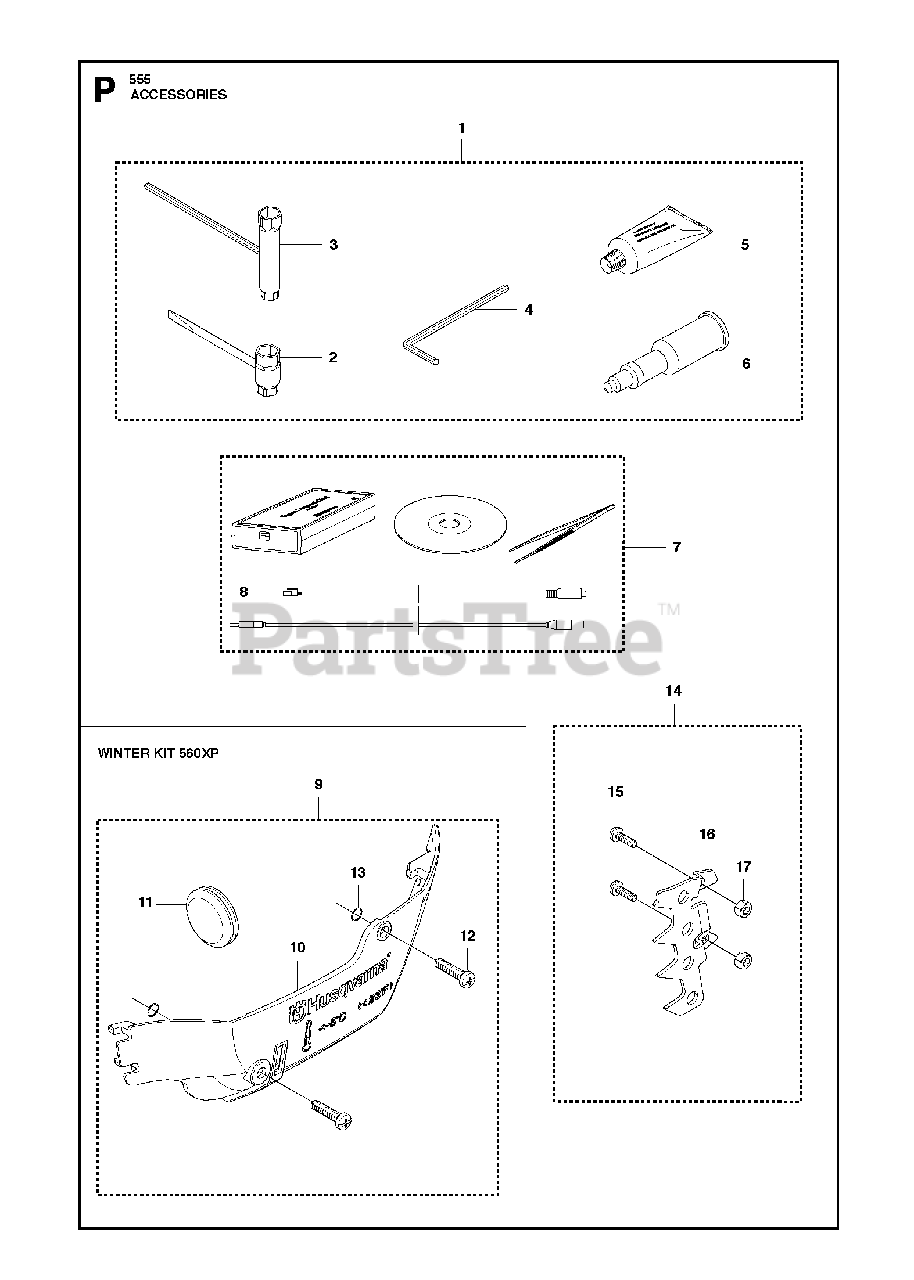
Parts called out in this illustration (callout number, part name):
2	COMBINATION WRENCH
3	L-SPANNER
4	L-SPANNER
5	GREASE
6	Grease Gun
7	SERVICE TOOLS
8	CABLE ASSY
9	WINTER KIT
10	WINTER COVER
11	PLUG
12	SCREW
13	O-RING
14	SPIKE OUTER
15	SCREW
16	SPIKE OUTER
17	NUT
